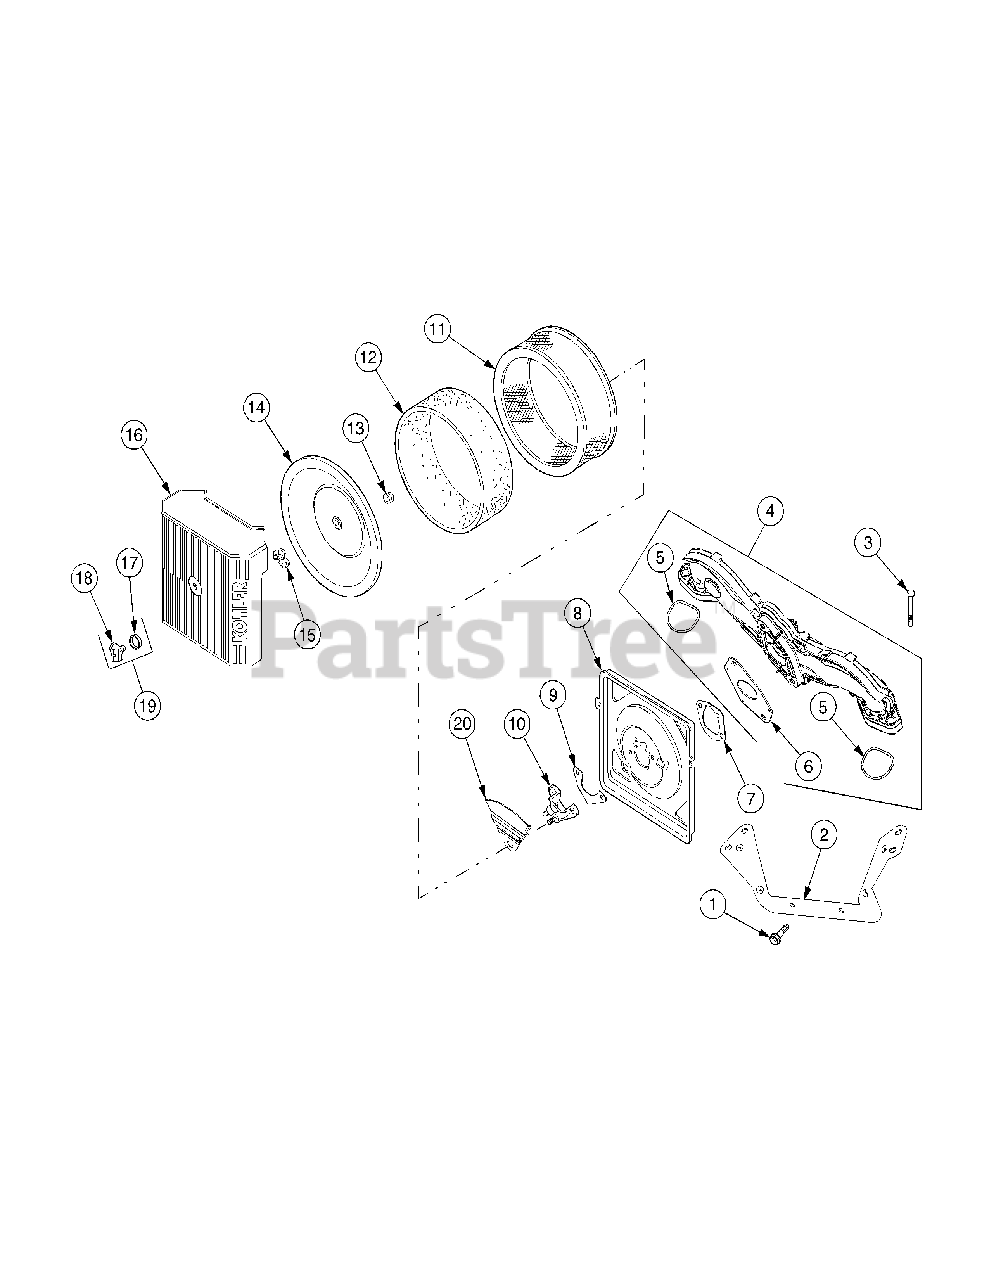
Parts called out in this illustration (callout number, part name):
1	Screw, Hx Flange, M5-0.8 x 10
2	Bracket, Air Cleaner Base
3	Screw, Hx Flange, M6-1.0 x 40
4	Manifold, Intake
5	O-Ring, Intake Port
6	Gasket, Intake Manifold
7	Gasket, Air Cleaner Base
8	Base, Air Cleaner
9	Gasket, Fuel Spit-back Cup
10	Cup, Spit-back w/Stud
11	Element, Air Cleaner
12	Element, Precleaner
13	Seal, Breather
14	Cover, Inner Air Cleaner
16	Cover, Air Cleaner
17	Kit, Knob w/Seal
20	Baffle, Fuel Spit-back
